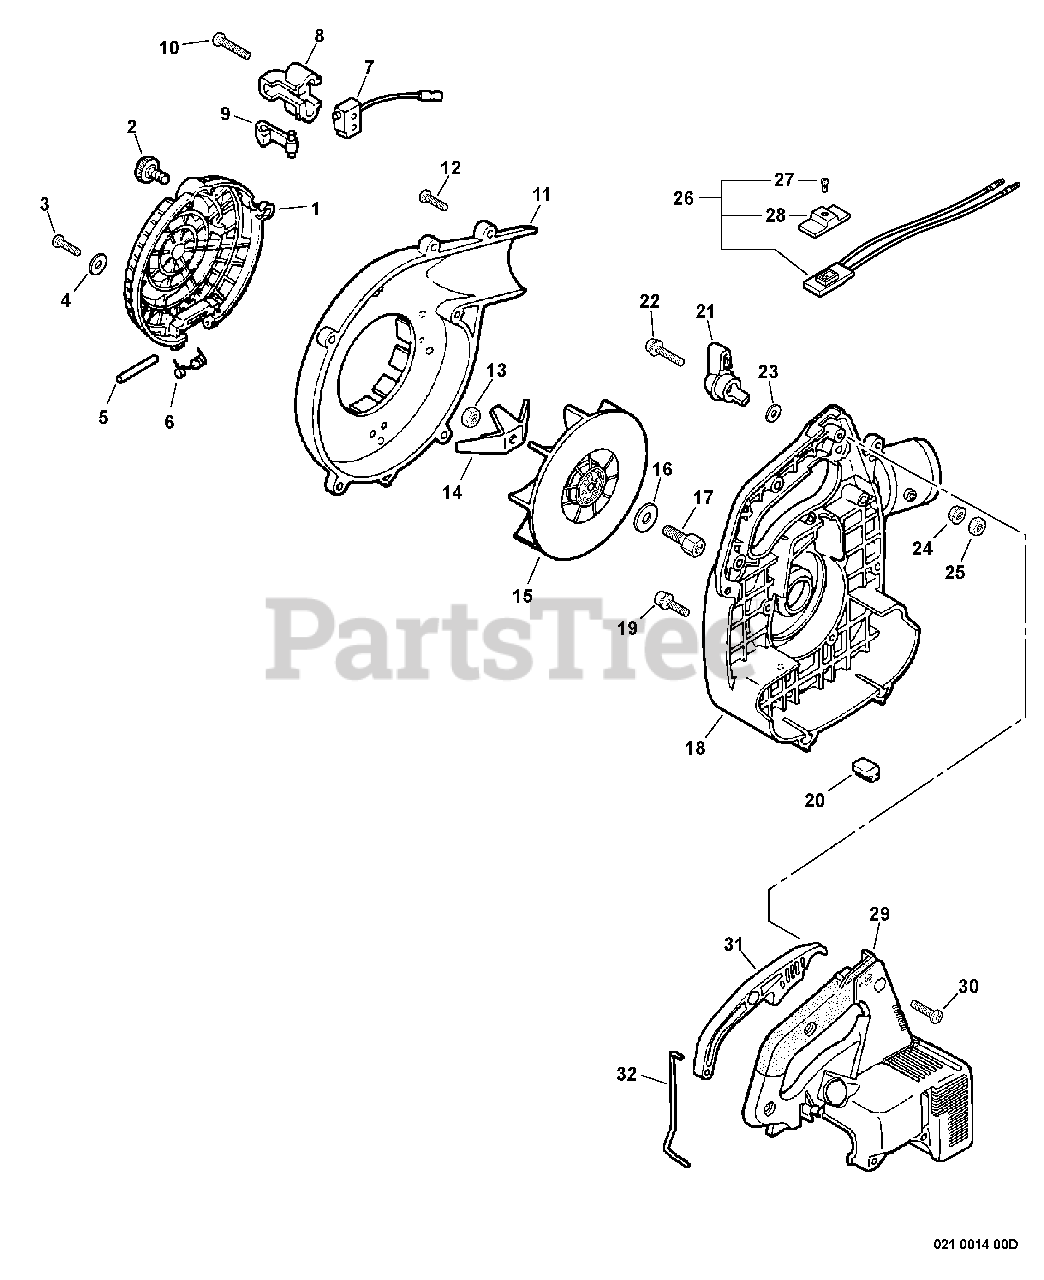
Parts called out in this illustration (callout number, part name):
1	COVER, INTAKE
2	THUMBSCREW
3	SCREW 5×14
4	WASHER 5.5×12×0.8
5	PIN, INTAKE COVER
6	SPRING, COIL
7	SWITCH, INTERLOCK
8	BRACKET, SWITCH
9	LEVER, SHUT OFF ACTUATOR
10	SCREW 4×22
11	COVER, FAN - LEFT -- ORANGE
12	SCREW, TAPPING 5×20
14	SHREDDER
17	HUB, FAN
18	COVER, FAN - RIGHT -- ORANGE
19	SCREW 4×22
21	LEVER, CRUISE CONTROL
22	SCREW 5×25
23	WASHER 5.5×12×0.8
24	NUT, FLANGE M5
26	SWITCH, ON-OFF
27	SCREW 3×10
28	KNOB, SWITCH
29	COVER, ENGINE
30	SCREW, TAPPING 5×20
31	TRIGGER, THROTTLE
32	ROD, THROTTLE
